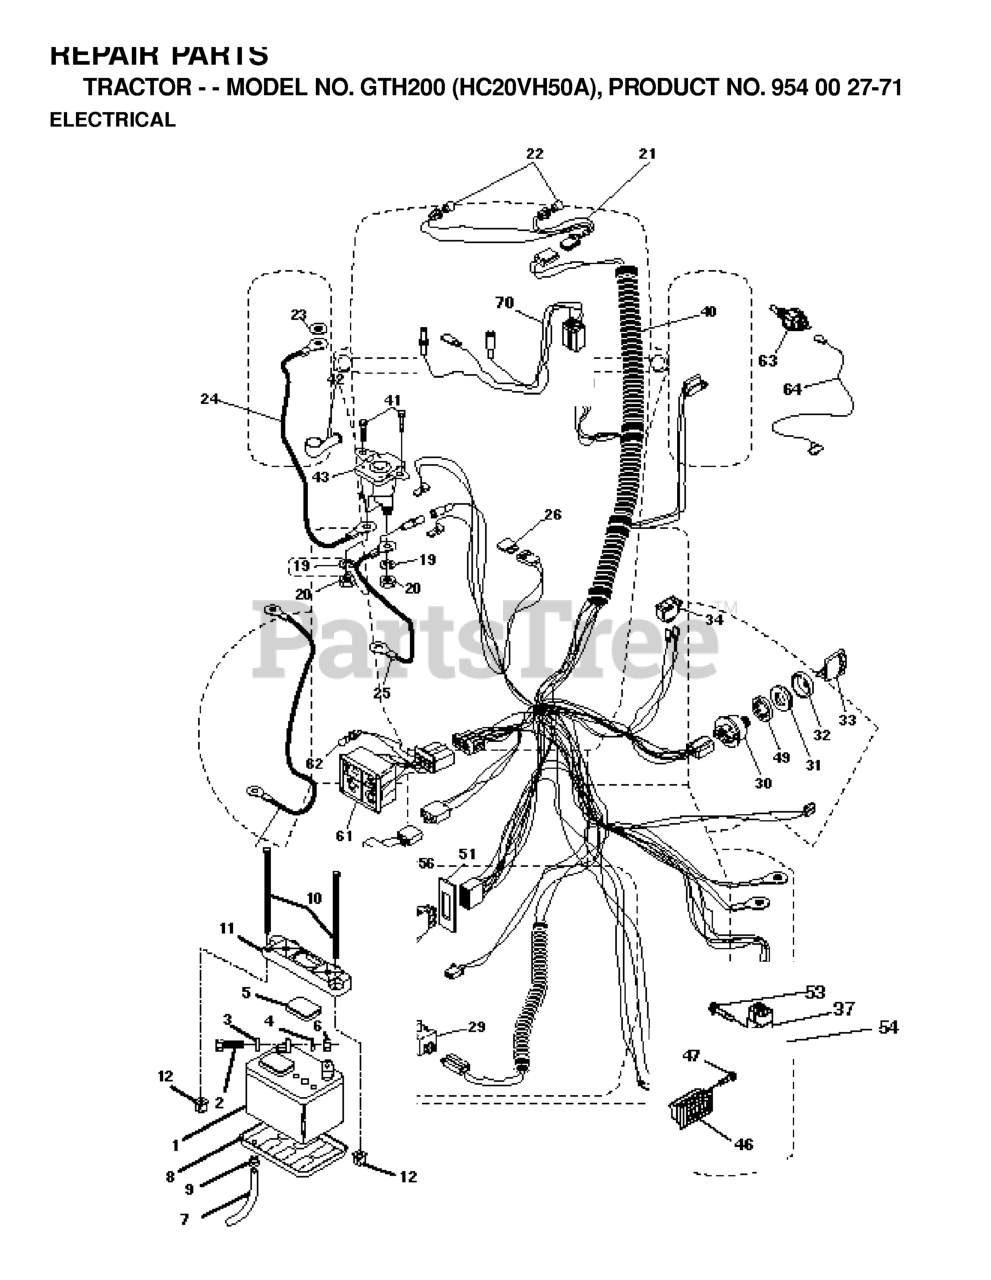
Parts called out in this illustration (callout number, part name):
1	BATTERY
2	BOLT.HEX.1/4.X.3/4.DICHROMATE
3	LOCKWASHER
5	CAP BATTERY NLA
6	NUT
7	PLASTIC TUBE
8	BATTERY TRAY T
9	HOSE CLAMP T
10	BOLT 1/4-20 X 7.5
11	HOLDDOWN, BATTERY, DASH MOUNT
12	NUT, PUSH NYLON 1/4" BATTERY
19	LOCKWASHER
20	NUT
21	HARNESS LIGHT SOCKET
23	Washer, Lock, Internal Tooth 1/4
24	BATTERY CABLE GT
25	CABLE-BATTERY YTV
28	CABLE T
29	RP.SWITCH.PLUNGER.NC.GRAY
30	IGNITION SWITCH
31	NUT, IGNITION
32	COVER SWITCH KEY
33	KEY MLD GEN DELTA
37	SWITCH INTERLOCKT
41	SCREW
42	TERMINAL COVER
43	SOLINOID
46	HOUR METER T
47	Screw 10-24 x 1/2 Black
49	Washer, Lock Internal Tooth 5/8
50	SWITCH-PTO
51	FRAME RETAINING RING
53	SCREW **
54	Nut, Hex, Keps #10-32 UNF
56	SENSOR LOW VOLTAGE
61	LIGHT PACKAGE
62	BULB LIGHT T
63	SWITCH, OIL PRESSURE
70	ENGINE HARNESS
